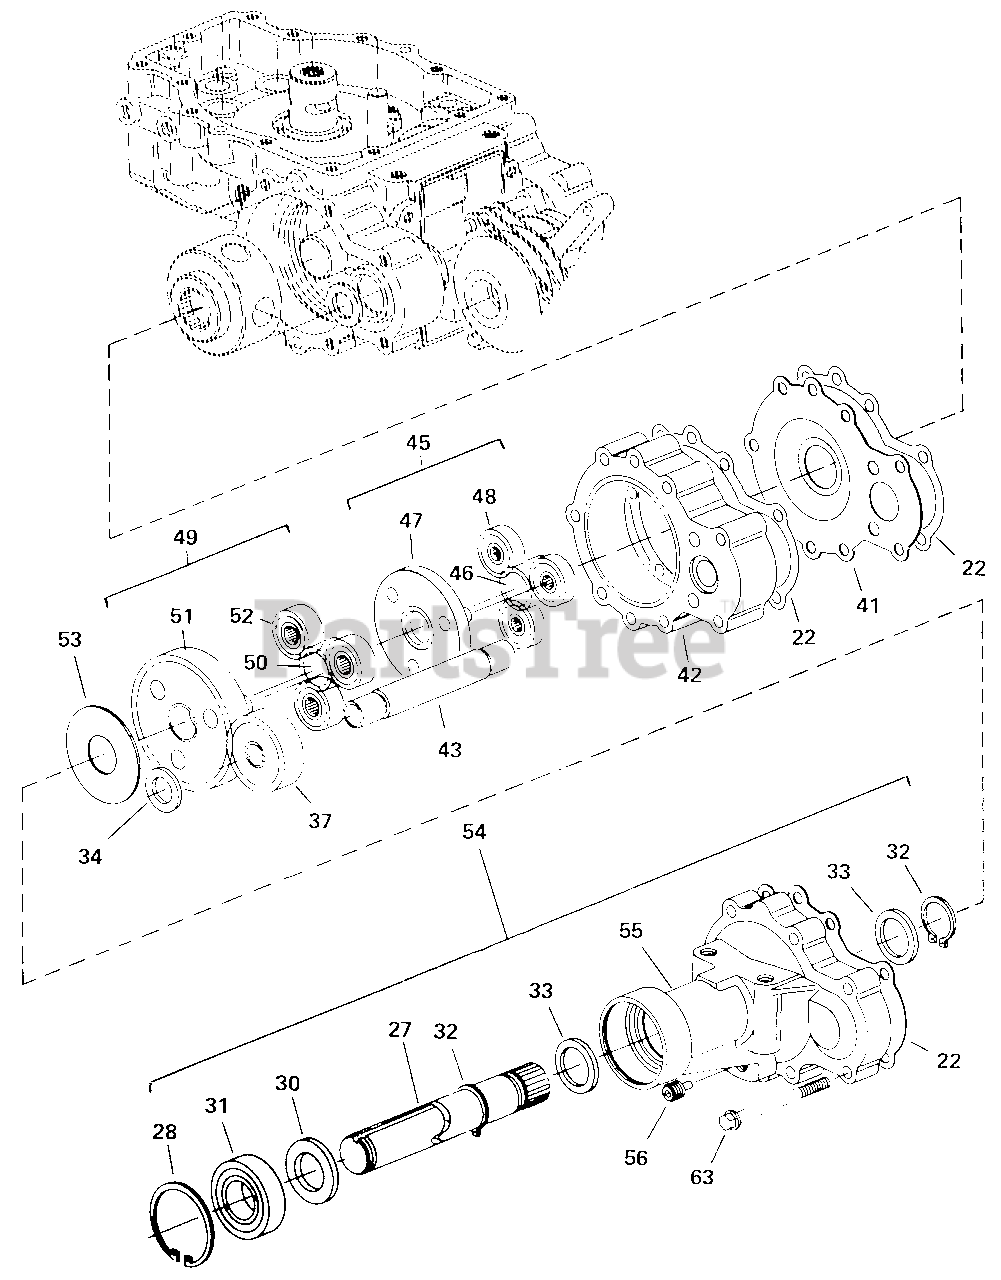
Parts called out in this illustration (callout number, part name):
22	GASKET, Axle Housing
27	SHAFT, Axle
28	RETAINING RING, Internal
30	LIP SEAL, Radial
31	BEARING, Ball
32	RING, Retainer
33	WASHER, Thrust
37	LOCK GEAR, Differential
41	PLATE, Wear
42	RING GEAR, A & B S/A, 57T
43	BRAKE SHAFT-A
45	PLANETARY GEAR, First, Subassembly (Incl. Ref. Nos. 46, 47 & 48
49	PLANETARY GEAR, Second, A & B S/A (Incl. Ref. Nos. 50, 51 & 52
53	WASHER, Thrust
54	AXLE HOUSING, S/A-A
55	HOUSING, Axle-A
56	PLUG, Magnetic
63	CAPSCREW, 1/4-20 Hex Flange x 2-3/4
63	Gasket Overhaul Kit (Incl. Ref. Nos. 19, 22 & 24)
